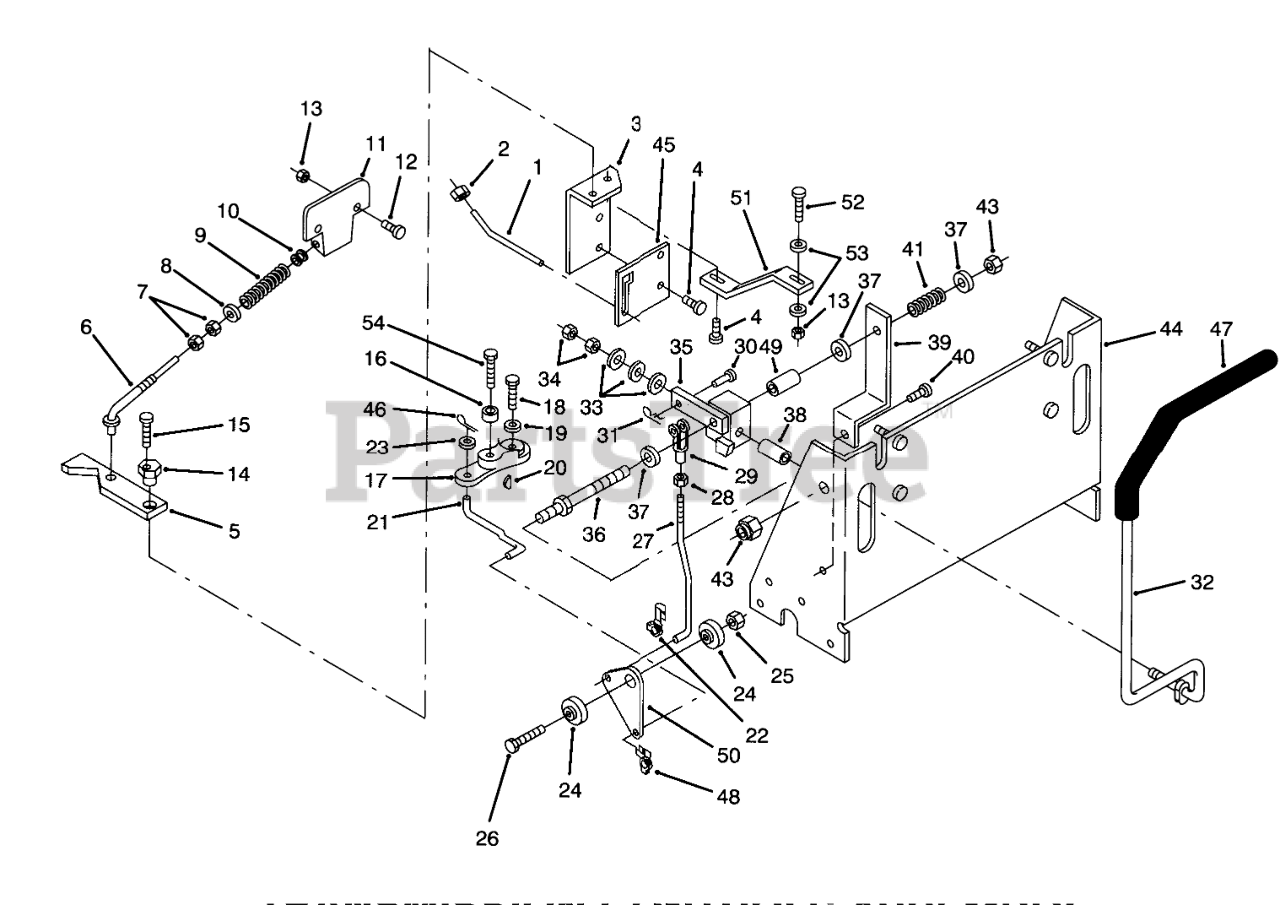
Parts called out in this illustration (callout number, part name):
1	LEVER-TOW VALVE
2	NUT-LOCK, NI
3	Bracket RH
4	Bolt
5	Arm
6	ROD-NEUTRAL RETURN
7	NUT-JAM
8	WASHER-FLAT
9	SPRING COMPRESSION
10	NYLINER BUSHING
11	Bracket
12	SCREW-HH
13	NUT-LOCK, NI
15	Bolt
16	SPACER
17	Arm-Control, RH
18	SCREW-HH
19	WASHER-FLAT
20	KEY WOODR 1/8X1/2 DI
21	LINK-R.H.
22	CLIP-CLEVIS L.H.
23	WASHER-FLAT
24	SPACER-CLUTCH LINK
25	NUT-LOCK, NI
26	SCREW-HH
27	ROD-HYDRO CTRL. ADJ.
28	NUT-JAM
30	Pin
32	R/H STRG LEVER B
33	SPRING-BELLVILLE
34	Jam Nut
35	Lever Pivot RH
36	SHAFT-PIVOT
37	WASHER-FLAT
38	BUSHING-STR LVR PVT
39	Bracket-Retainer
40	Screw
41	SPRING
43	NUT-LOCK, NI
44	Lever Support
45	PLATE-TOW VALVE L
46	PIN-COTTER
47	Grip
48	CLIP-CLEVIS R.H.
49	BUSHING
50	PLATE-CONTROL PIV
52	SCREW-HH
53	WASHER-PLAIN
54	SCREW-HH
